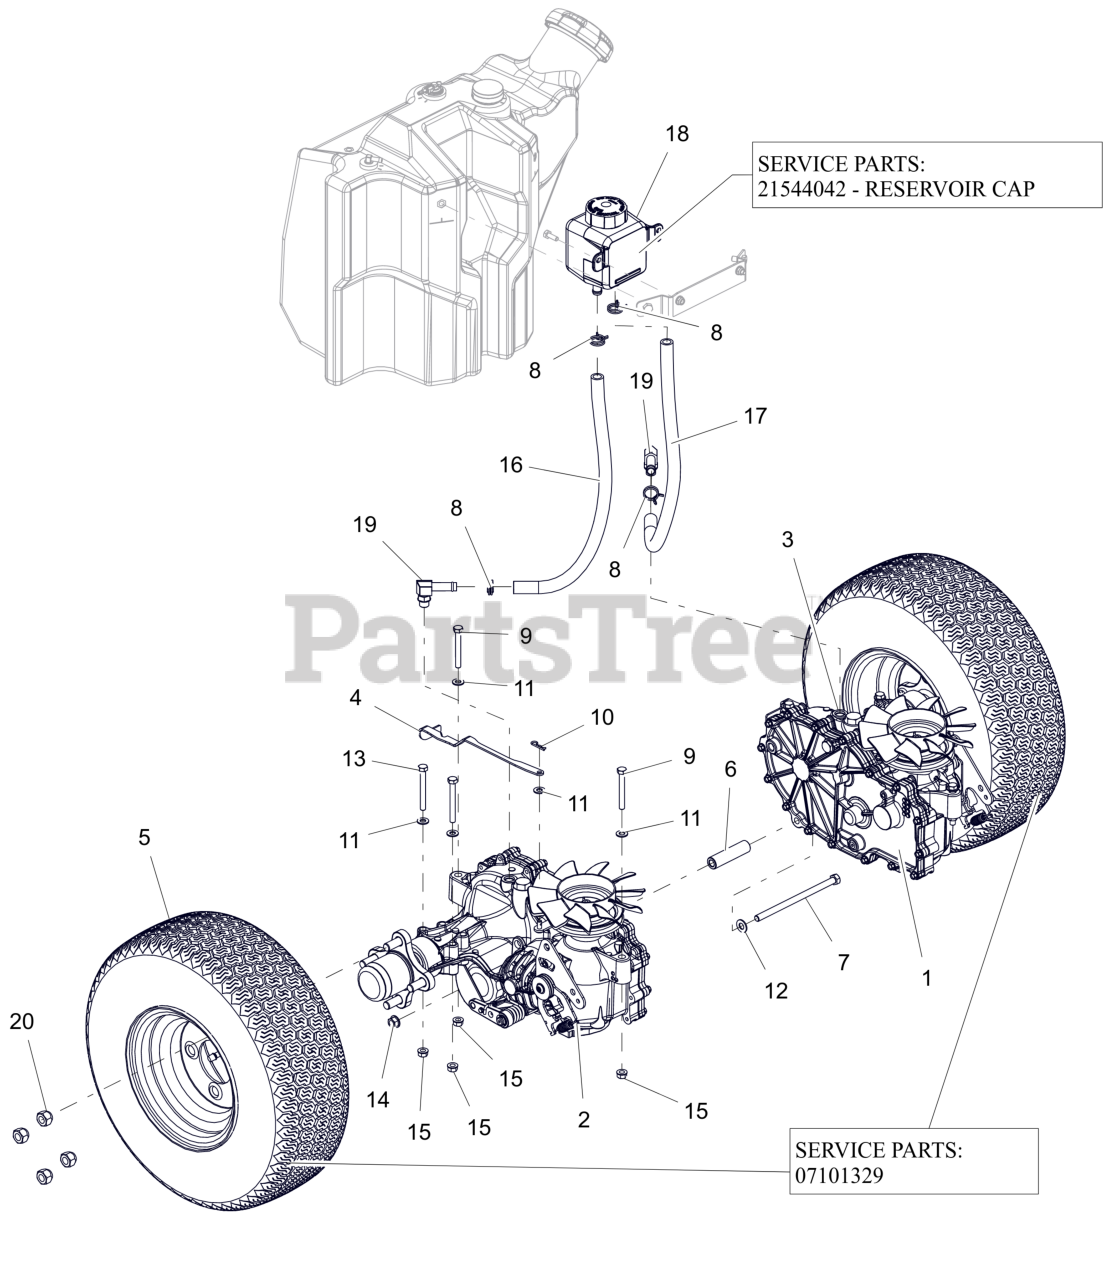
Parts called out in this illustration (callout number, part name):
1	TRANSAXLE- ZT3100 - LH
2	TRANSAXLE- ZT3100 - RH
3	BRKT, HYDRO DUMP - LEFT
4	BRKT, HYDRO DUMP - RIGHT
5	ASM, WHL/TIRE 18X6.50-8
6	SHAFT, CROSS BRACE
7	BLT, HEX .38-16X6.50 G5 ZCC
8	3/4 WIRE HOSE CLMP ZC
9	BLT, HEX 0.3125-18X2.5 GR5 ZCC
10	PIN, HAIR #213 .08X1.19 ZCC
11	WSHR,FLT .344X.688X.065 ZCC
12	WSHR,FLT .406X.812X.065 ZCC
13	BLT, HEX .31-18X2.75 G5 ZCC
14	NUT-LK-CTR-FLG .375-16 GF ZCC
15	NUT,LK-CTR-FLG .31-18 GF ZCC
16	HOSE, OVERFLOW 19"
17	HOSE, OVERFLOW 20"
18	TANK, HYDRO OVERFLOW 700 ML
19	FITTING, HYD (90 DEG)
20	NUT, WHEEL .50-20 ZCC
